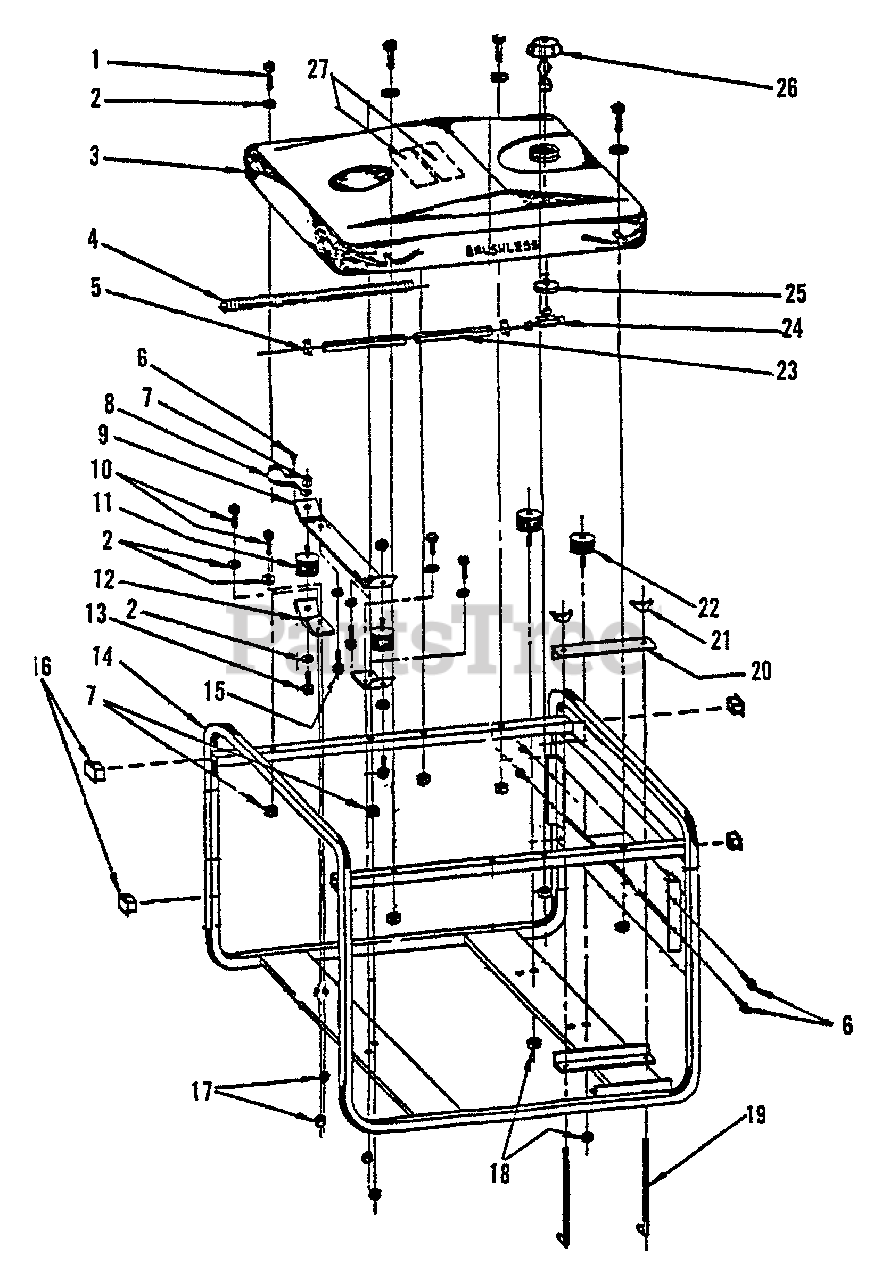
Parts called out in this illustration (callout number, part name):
1	BOLT - 5/16-18 X 1-1/2"
2	LOCKWASHER - 5/16"
3	TANK, FUEL - 6 GALLON
4	CONDUIT - 12"
5	CLAMP - 1/4"
6	SCREW - 10-24
7	LOCKNUT - 5/16-18
8	STRAP - GROUND
9	RAIL, FOCUS
10	5/16-18X7/8 HHS
11	ISOLATOR, VIBRATION
12	BRACKET, FOCUS
13	5/16-18X5/8 HHS
14	FRAME
15	5/16-18X3/4 HHS
16	PLUG, END
17	LOCKNUT - 5/16-18
18	LOCKNUT - 3/8-16
19	BOLT, BATTERY HOLD DOWN
20	BRACKET, BATTERY
21	WINGNUT - 1/4"
22	ISOLATOR, VIBRATION
23	LINE, FUEL - 24"
24	VALVE, FUEL TANK
25	GROMMET
26	CAP, FUEL
27	LABEL - SAFETY
